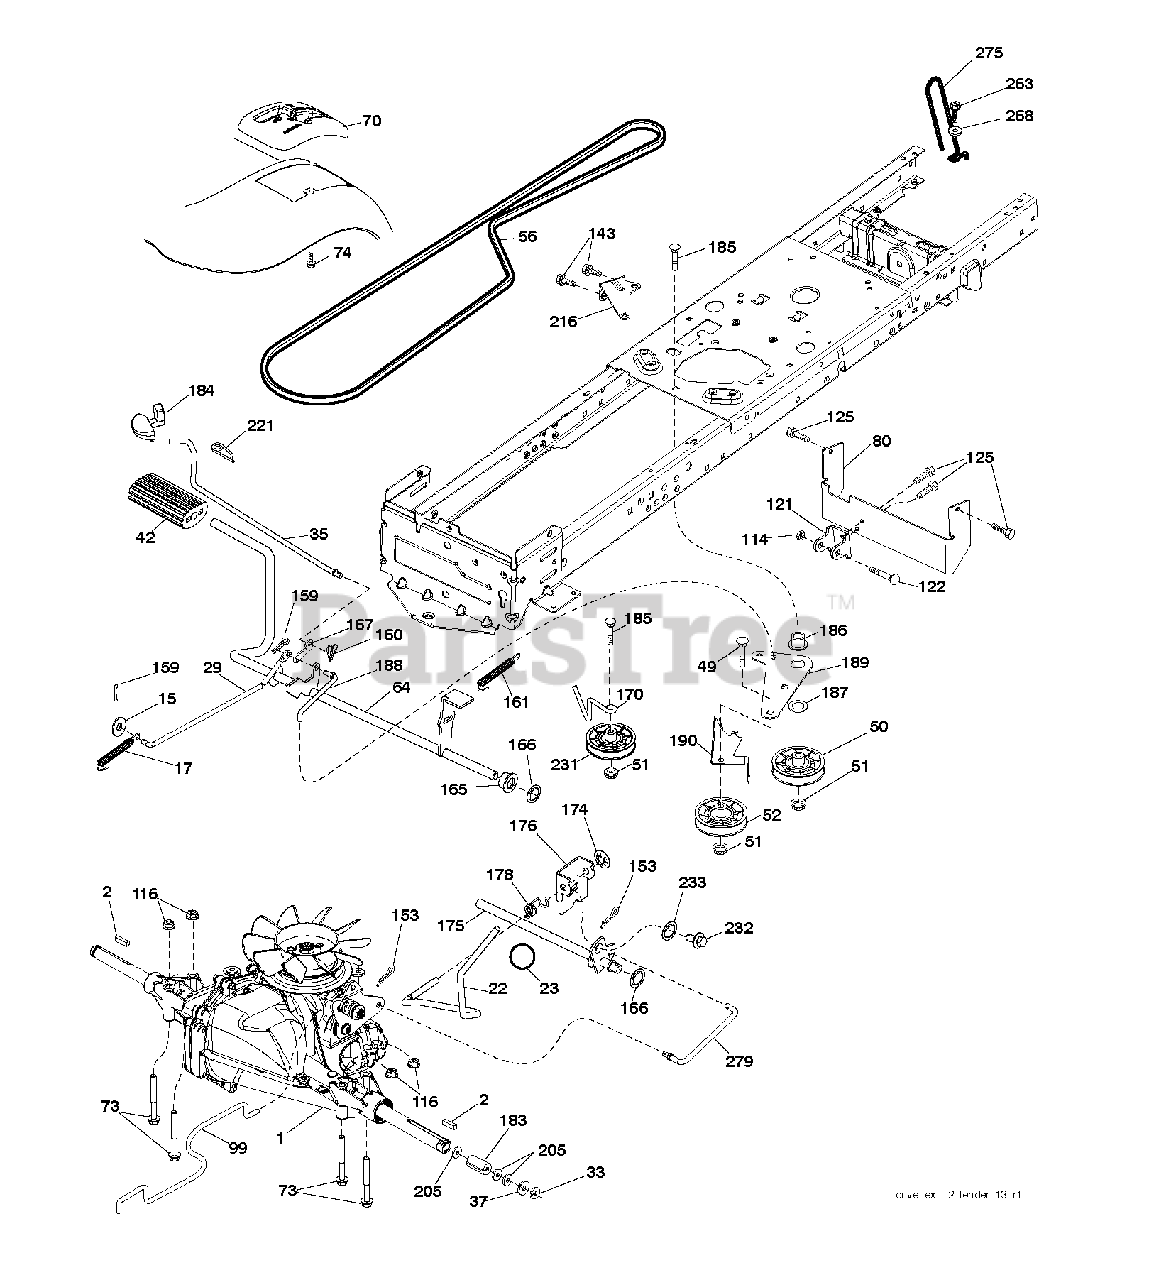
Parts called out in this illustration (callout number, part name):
2	SQUARE KEY
17	SPRING.BRAKE.HG3000/3500
22	ROD.SHIFT.FENDER.TLT.2006
23	KNOB.DUCKHEAD.1/2
29	ROD.BRAKE.T2.TEX
33	E-RING LT
35	ROD, BRAKE, PARK
42	PEDAL COVER T
49	BOLT
50	IDLER.FLAT.910.OFFSET
51	NUT LOCK FLG 3/8-16 UNC
52	IDLER.V-GROOVE.910.OFFSET
64	SHAFT.ASM.PEDAL.BRAKE.
70	CONSOLE.SHIFT.STL.HYD.BLACK
73	BOLT HEX 5/16-18 GR 5
74	SCREW.HI-LO.CONSOLE
80	STRAP.TORQUE.FS.T2
99	ROD.ASM.BYPASS.SPRING.T2.FS
114	NUT.71038.31-18.HEX.NYLOCK
116	NUT LOCK HEX FLANGE 5/16-18
121	BRACKET STRAP TORQUE
122	BOLT.5/16-18X2.5
125	SCREW
153	RETAINER M
159	COTTER PIN
160	RETAINER CLIP
161	SPRING, RETURN LT
165	BUSHING.SHAFT.BRAKE.HAND
166	NUT.PUSH.625.2006
167	LATCH.BRAKE.SPRING
170	KEEPER.CENTER SPAN.1.688
174	NUT.PUSH.500.2006
175	SHAFT.ASM.SHFT.T2.TLT
176	ARM.CLEVIS.ROD.SHIFT
178	SPRING.SHIFT.GT2006
183	SPACER, AXLE PVST
184	HANDLE PARKING BRAKE
186	SPACER.RETAINER
187	WASHER 12/32X2X10GA
188	LINK.CLUTCH.GROUND.DRIVE
189	BELLCRANK.GROUND.DRIVE.TEX.
190	KEEPER.BELLCRANK.DRIVE
216	BRACKET.PULLEY.IDLER.W/TEX
221	RETAINER.SPRING.CLIP.H
231	IDLER.V-GROOVE.1.688.OFFSET
232	BOLT FIN HEX 7/16-14 X 1
233	WASHER SERRATED
263	SCREW, 3/8-16X3/4
268	WASHER
279	LINK SHIFT
